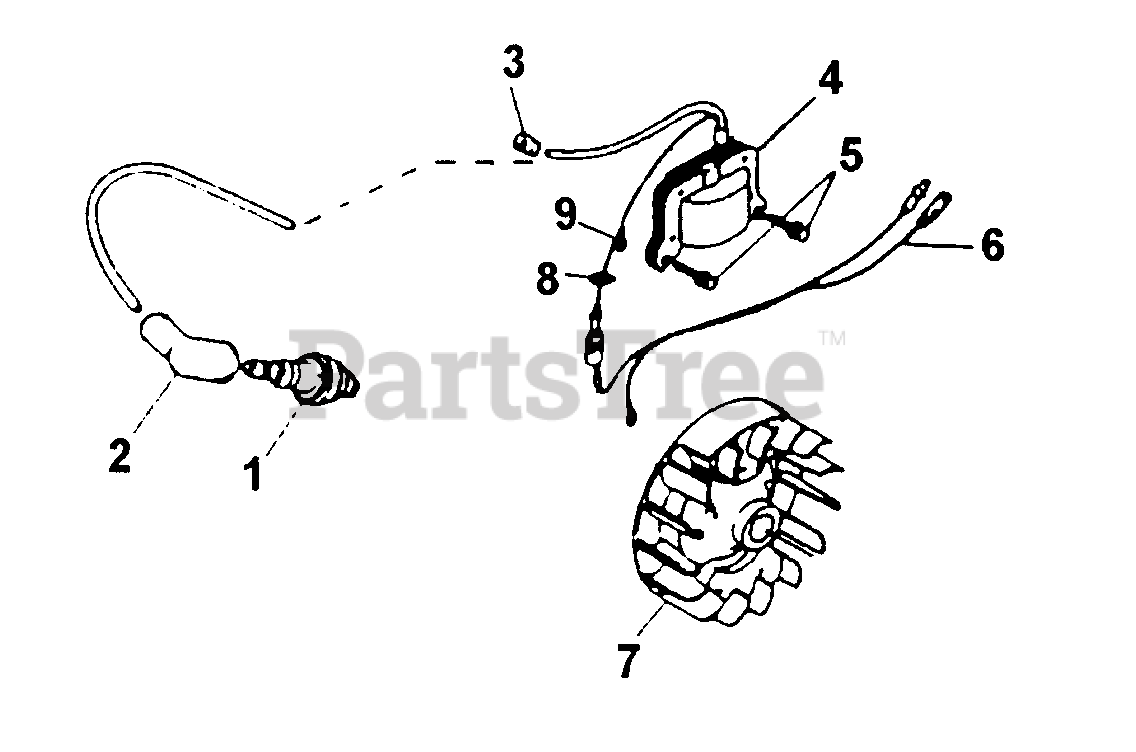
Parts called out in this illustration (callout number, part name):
1	SPARK PLUG
2	CAP, PLUG
4	COIL ASSY
5	BOLT & WASHER
6	LEAD WIRE
